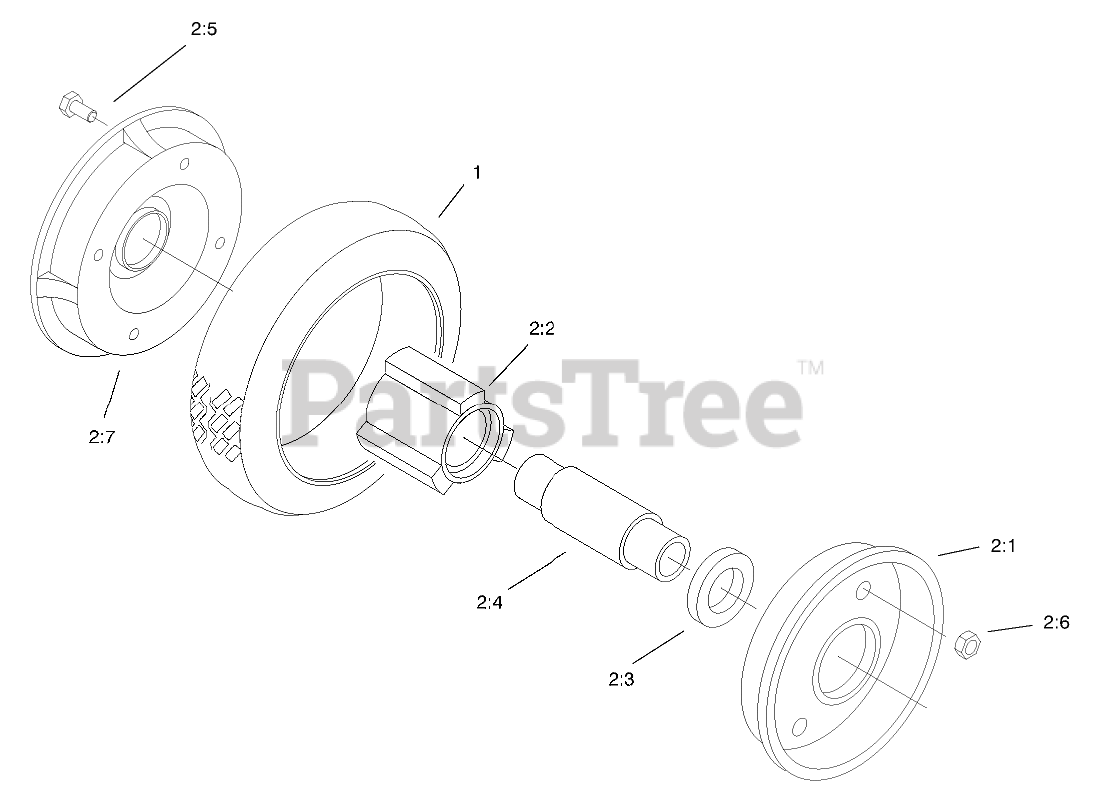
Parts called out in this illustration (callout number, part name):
2	ASM-Wheel & Tire
2:1	Wheel-Half
2:2	HUB-BEARING
2:3	Bearing-Wheel
2:4	SPACER-BEARING
2:5	SCREW-HH
2:6	NUT-LOCK, NI
2:7	Wheel-Half
